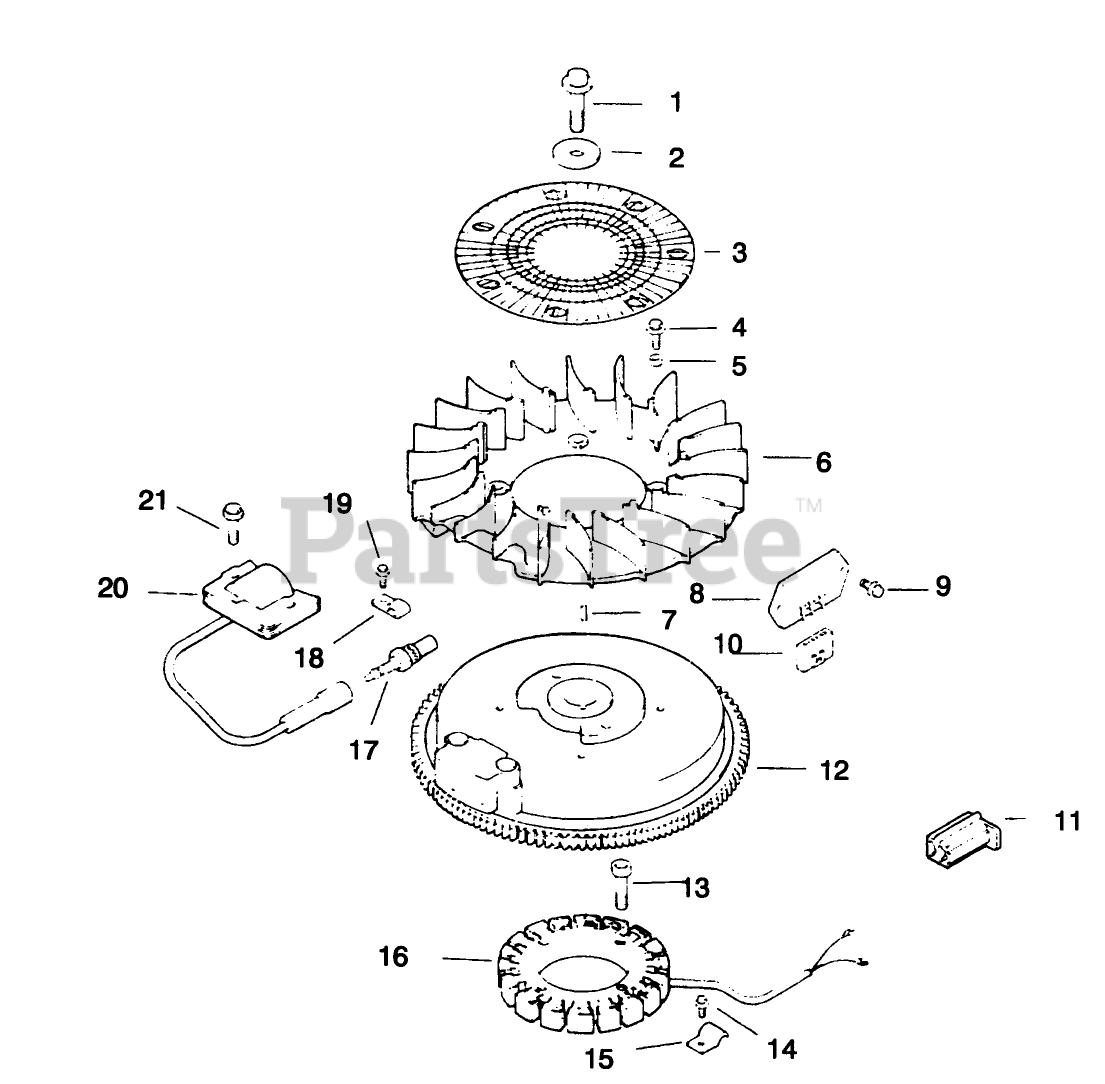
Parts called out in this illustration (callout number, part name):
1	Screw
2	Washer-Flat
3	Screen-Grass
5	Spacer-Fan
6	Fan (Only On: 72042, 72063, 72062, 72043)
8	Rectifier-Unrelated
10	Connector
11	Connector
12	Flywheel ASM (Only On: 72042, 72063, 72062, 72043)
15	Clip-Stator Harness (Only On: 72042, 72063, 72062, 72043)
16	Stator-15 amp
17	Spark Plug
20	Module-Ignition
